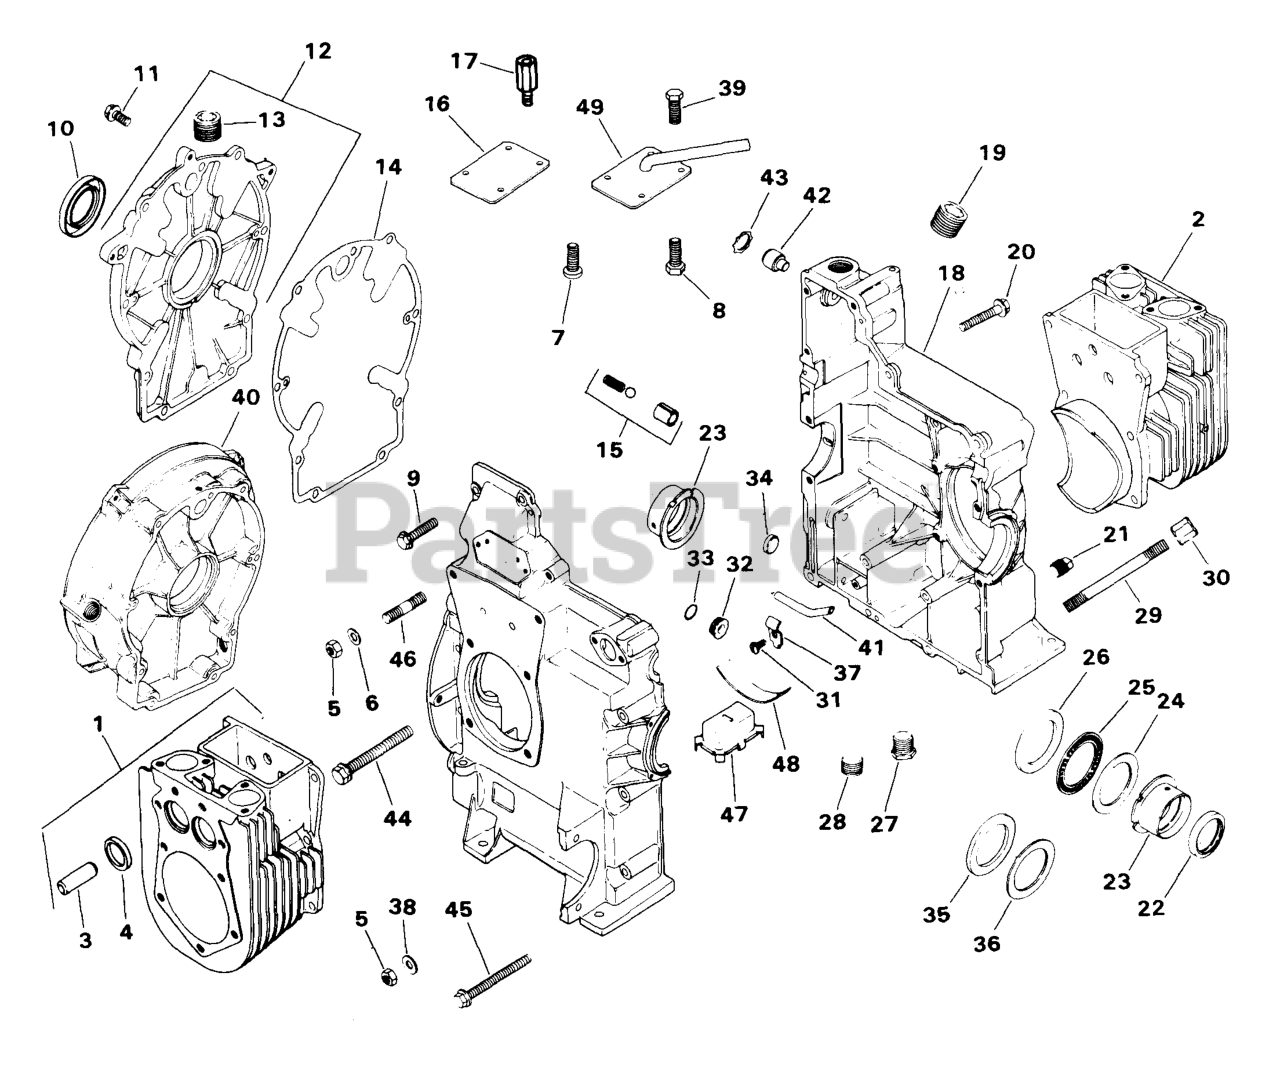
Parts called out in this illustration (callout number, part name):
1	KIT, CYLINDER BARREL - (#DSC)
2	KIT, CYLINDER BARREL
3	GUIDE - USE 52 316 08
4	INSERT - (#DSC)
5	NUT, 5/16-18 GRADE 5 USE 25 100 22-S
6	WASHER, FLAT 5/16"
9	SCREW - DISCONTINUED
10	SEAL, OIL (KM)-USE 25 032 06-S
11	SCREW, WSH HD 5/16-18X1" - DISCONTINUED
12	KIT, CLOSURE PLATE - DISCONTINUED
13	PLUG, CTSK PIPE 1/8" USE 25 139 60-S
15	KIT, OIL RELIEF - DISCONTINUED
21	PLUG, SQ HD PIPE 3/8" USE 25 139 57-S
23	BEARING .010
23	BEARING .020
28	PLUG, PIPE CTSK 3/8" USE 25 139 62-S
31	SCREW, WSH HD TAP #10-32X7/16" USE 25 086 101-S
33	O-RING - DISCONTINUED
34	PLUG, CUP USE 25 139 46-S
37	CLAMP - DISCONTINUED
39	SCREW - DISCONTINUED
41	KIT - USE 82 755 29
42	SHAFT - DISCONTINUED
44	SCREW - DISCONTINUED
46	STUD - DISCONTINUED
47	KIT - USE 82 755 29
48	CLAMP - DISCONTINUED
